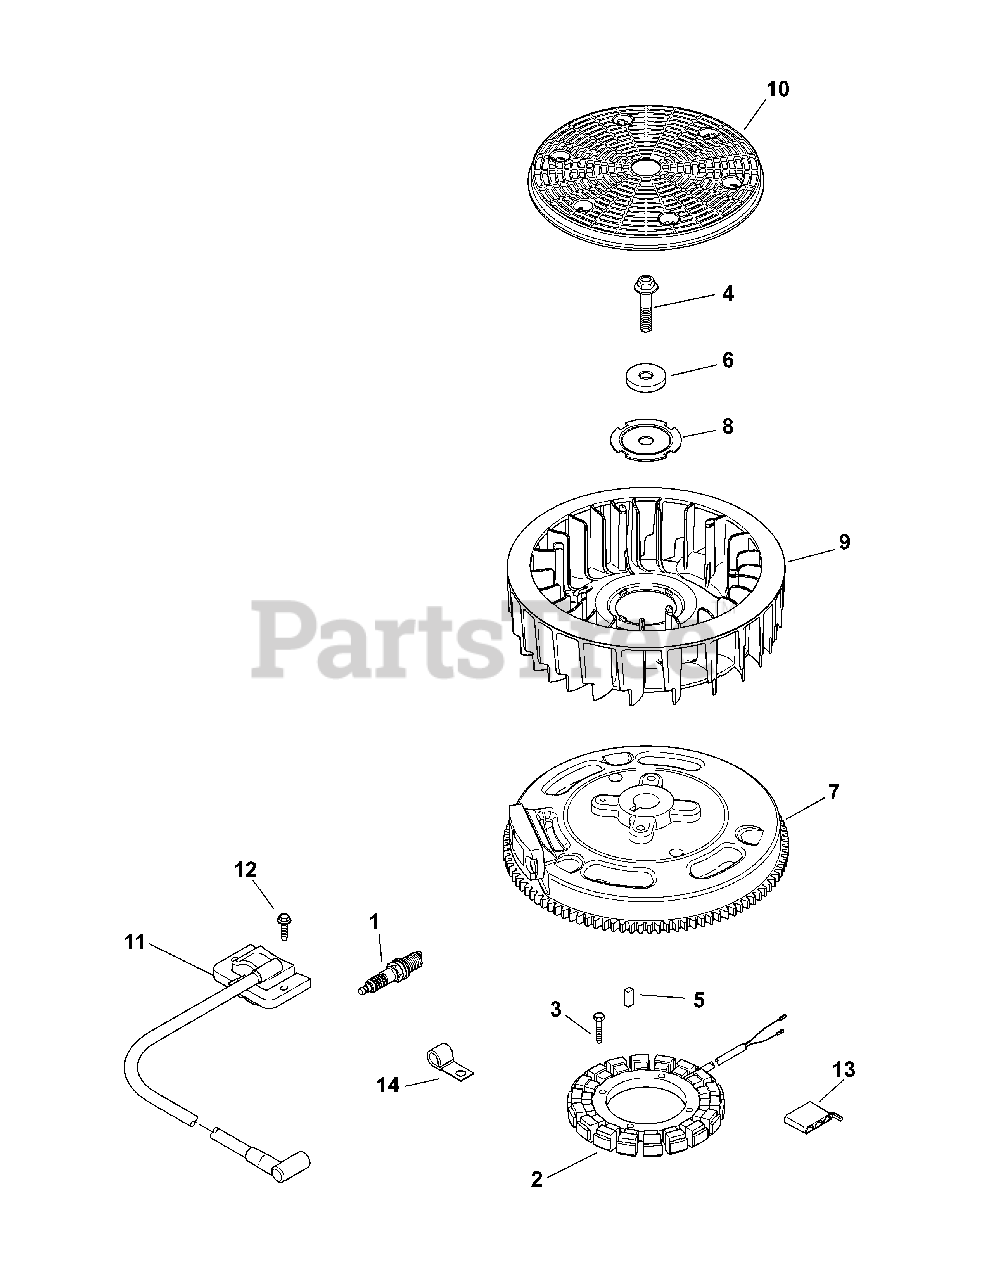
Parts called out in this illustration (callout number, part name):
1	Spark Plug
2	25 Amp Stator Assy. Kit
3	Thd. Frm. Screw, M5 x 0.8 x 30
4	Hex Flange Screw
7	Flywheel Assembly
8	Fan Mounting Plate
9	Fan
11	Ignition Module Kit
12	Flg. Thd. Frm. Screw, M5 x .8 x 20
